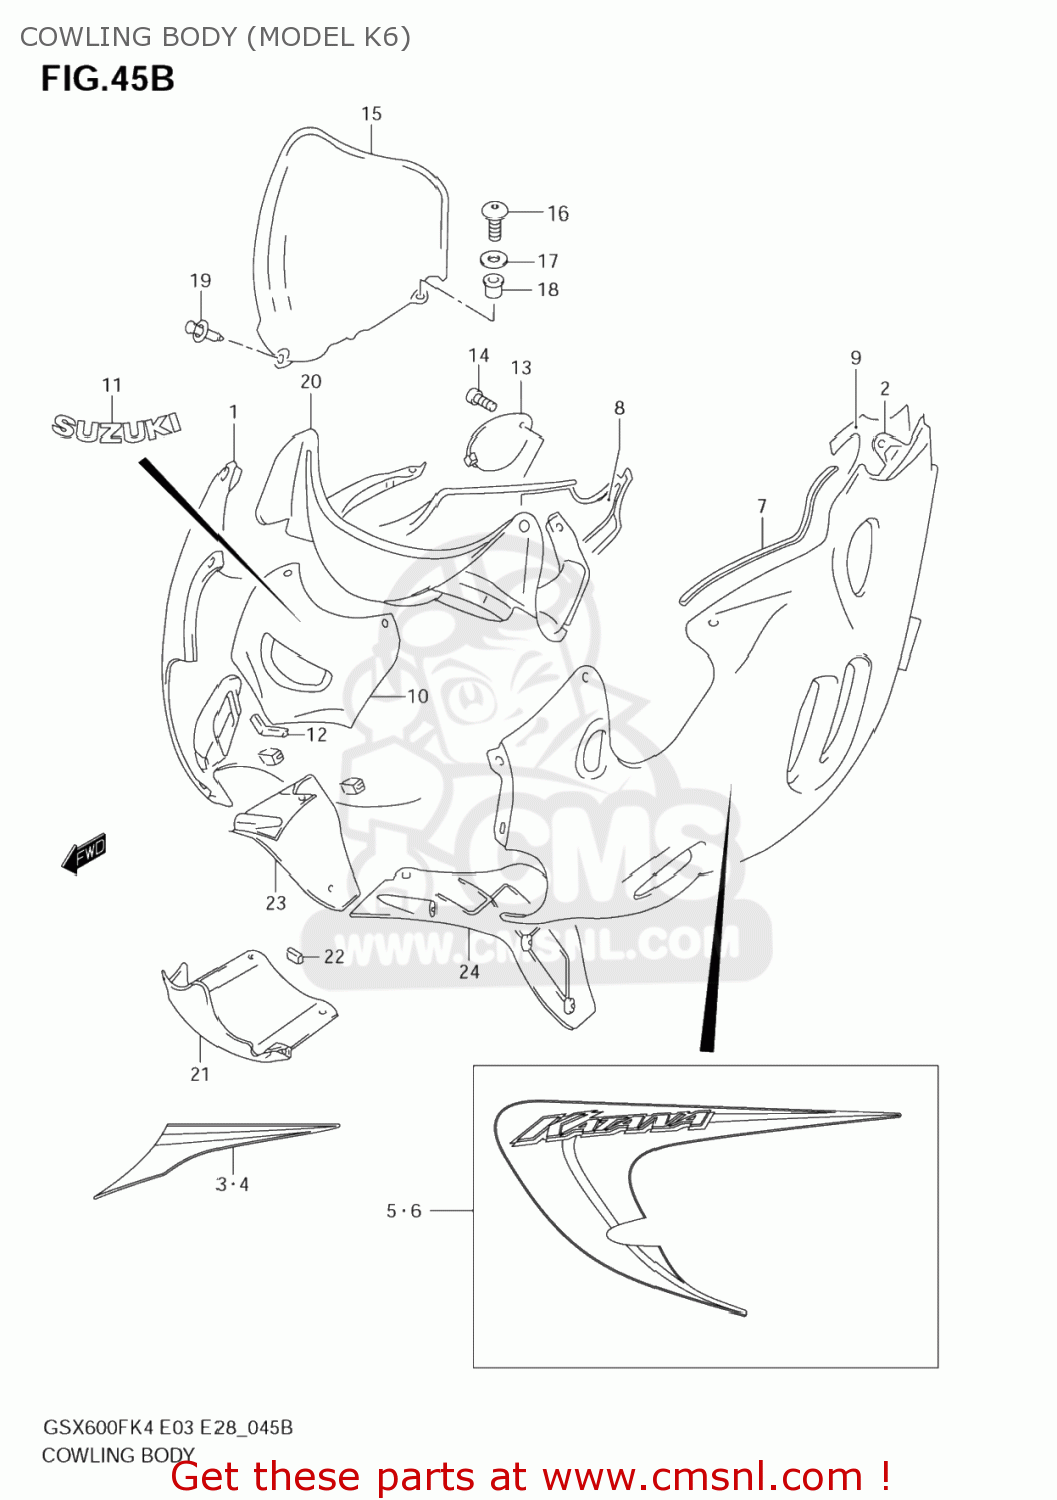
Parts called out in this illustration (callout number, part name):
1	COWLING ASSY,SIDE,R
2	COWLING ASSY,SIDE,L
3	TAPE,COWL SIDE UPR,R
4	TAPE,COWL SIDE UPR,R
5	TAPE,COWL SIDE,R
6	TAPE,COWL SIDE,L
7	MOLD,COWLING
8	SHIELD,COWLING COVER,R
9	SHIELD,COWLING COVER,L
10	PANEL,COWLING CTR UPR
11	EMBLEM,SUZUKI
12	CUSHION,CTR PANEL UPR
13	LID,OIL
14	SCREW(6X16)
15	WINDSCREEN
16	SCREW(5X14)
17	WASHER
18	NUT
19	CLIP(BLACK)
20	PANEL,METER
21	PANEL,COWLING CTR LWR
22	CUSHION,CENTER PANEL,LOWER
23	PANEL,COWLING INNER,R
24	PANEL,COWLING INNER,L
